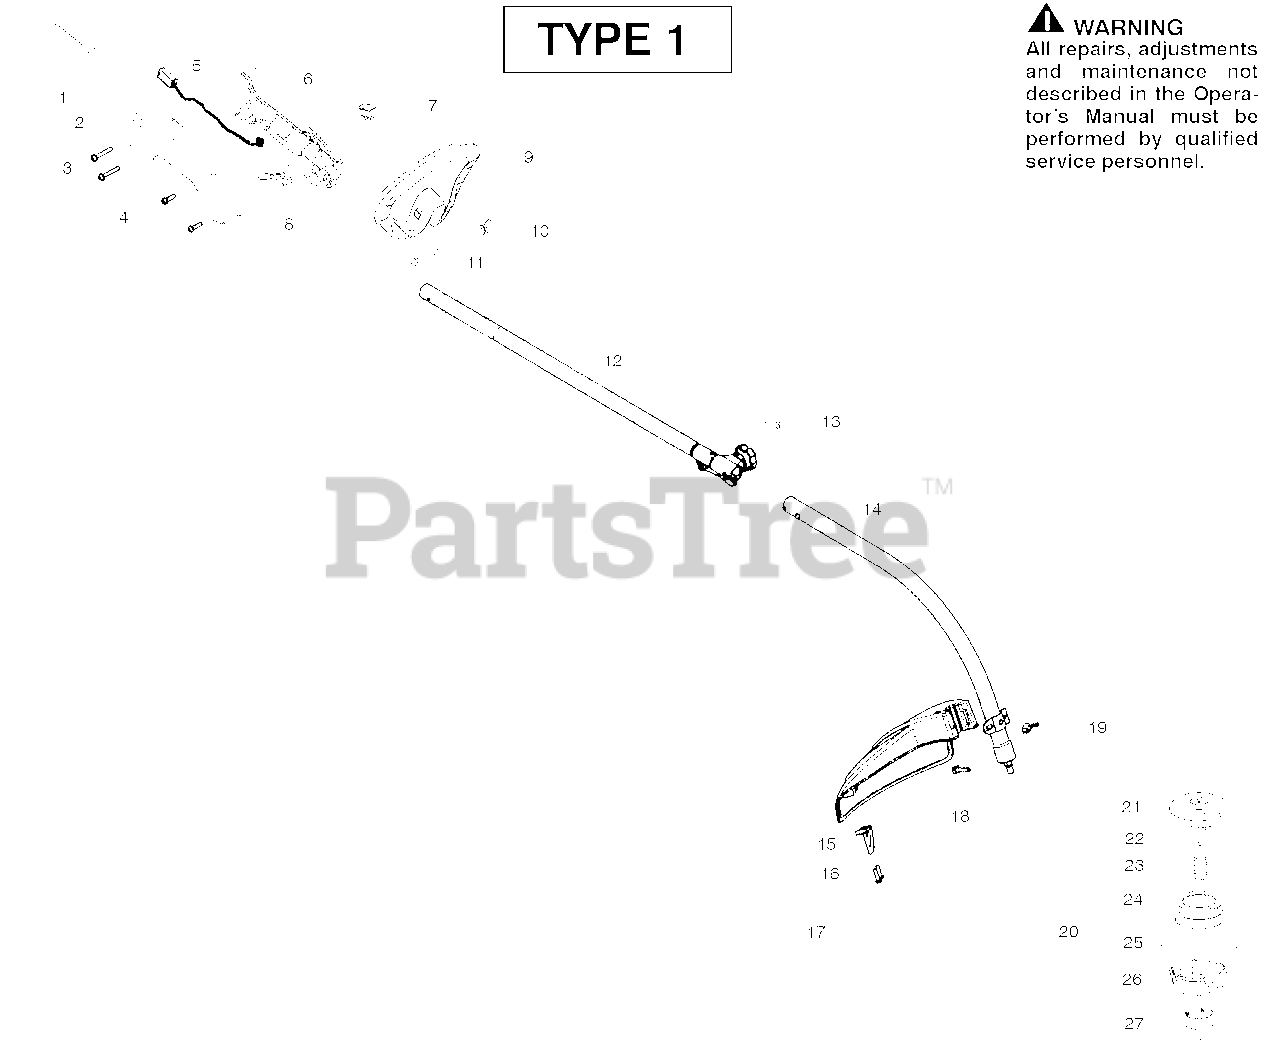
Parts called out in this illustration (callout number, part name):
1	Assy-Throttle Cable
2	Hsg.-Throttle (RH)
5	Assy.-Wire
6	Hsg. Throttle (LH)
7	Kit-Switch
8	Trigger-Throttle
9	Handle-Assist
10	Wingnut
12	Kit-Upper Shaft
14	Kit-Lower Shaft
15	Limiter-Line
17	Kit-Shield Assy.
19	Wingnut
20	Assy-TNG7
23	Spring P25
24	Assy-Wound Spool
25	Eyelet
26	Cover
27	Knob P25
